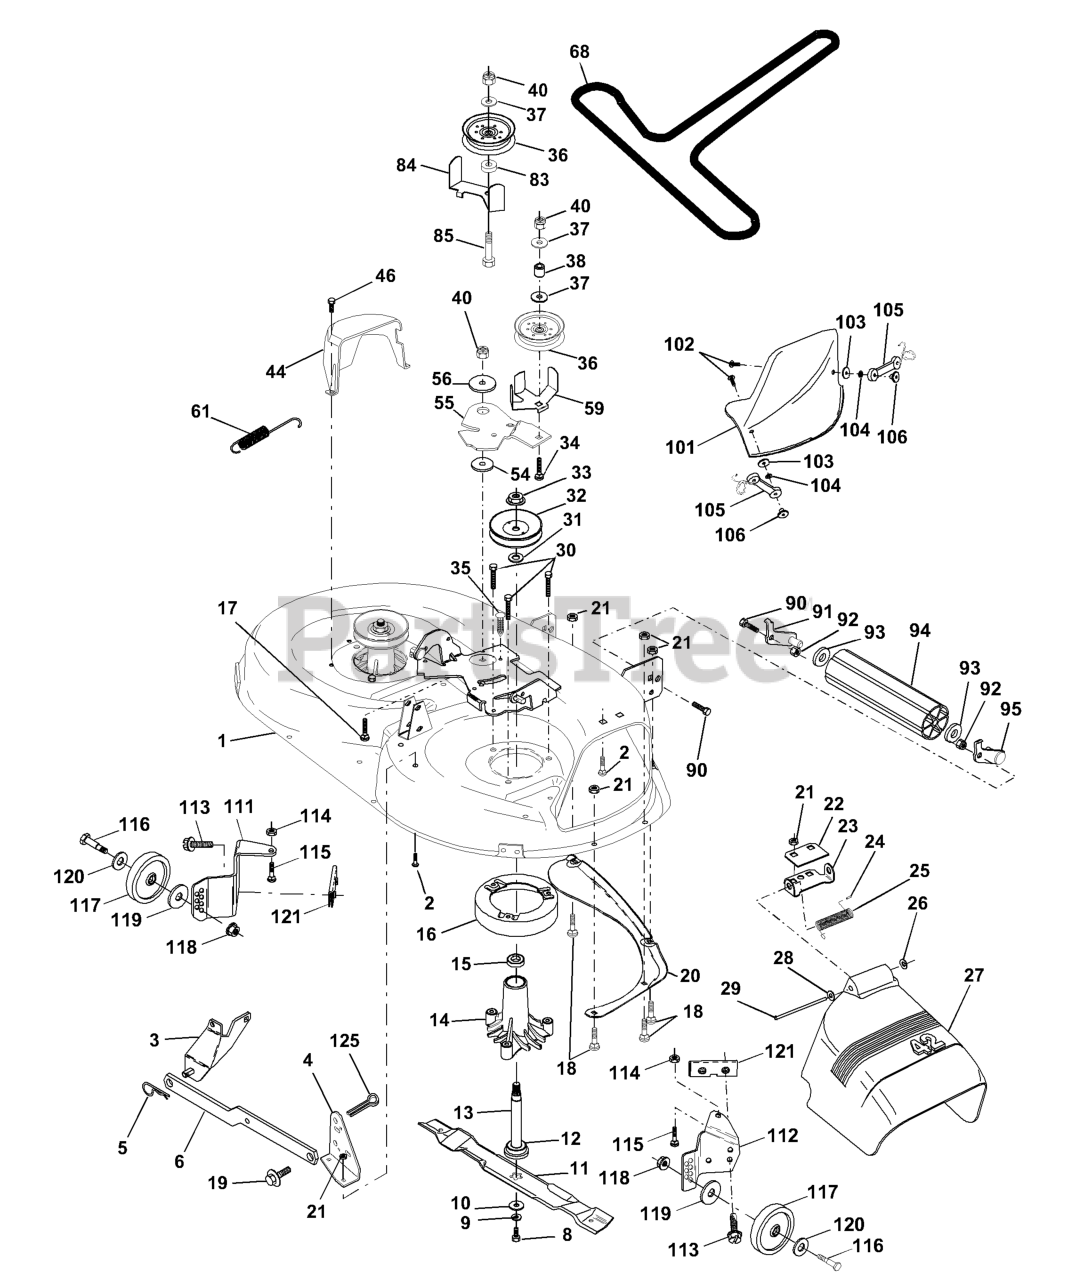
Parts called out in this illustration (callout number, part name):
1	DECK 42"
2	RP BOLT 5/16-18 X3/4 ZN/YEL GR
3	BRKT ASM SWAY BAR
4	BRKT DECK SW BAR
5	RETAINER-SPRNG RB
6	REAR SUSP ARM
8	BLADE BOLT
9	LOCKWASHER
10	WASHER.BLADE
11	BLADE.42".MULCH
12	BEARING.BALL.#6204.(MANDREL)
13	SHAFT ASM VENT
14	HOUSING.MANDREL.VENTED (MACHD)
16	STRIPPER
17	BOLT CARRIAGE
18	BOLT
19	BOLT SHD 5/16-18
20	BAFFLE
21	LOCKNUT
22	STIFFENER BRACKET
23	DEFLECTOR BRACKET
24	CAP-SLEEVE LT
25	SPRING TORSION
26	NUT PUSH M
27	SHIELD.DEFLECTOR.MOWER.42".BLK
28	Washer 11/32 X 5/8 X 16 Ga
29	ROD.HINGE
30	SCREW
31	WASHER
32	MANDREL PULLEY
33	NUT
35	FASTENER.XMAS.TREE
36	FLAT IDLER PULLEY
37	WASHER
38	IDLER SPRING SPACER
44	GUARD MANDREL LH BLACK
46	SCREW.1/4-20X5/8
54	HARDENED WASHER
55	IDLER ARM
56	SPACER RETAINER
59	GUARD, BELT
61	SPRING EXTENSION
68	V-BELT TRIPATH
84	KEEPER BELT
85	BOLT
90	BOLT
91	BRACKET LH (A)
92	NUT
93	Washer 17/32 X 7/8 X 16 Ga
94	NOSE ROLLER
95	BRACKET RH (B)
101	COVER MULCH 42"
102	SCREW
104	LOCKWASHER #10
105	LATCH ASSEMBLY
106	WELDNUT
111	BRACKET
112	BRACKET
113	SCREW.THDROL.5/16-18X3/4.TTY
114	NUT
115	BOLT.CARR.5/16-18X1/2
116	BOLT M
117	WHEEL.GAUGE.BLK.4.93
118	LOCKNUT
119	WASHER.5/16.FLAT.STE.STD.
120	Washer 17/32 x 15/16 x 12 Ga.
121	BRACKET.EXTRUDED.GAGE.WHEEL
125	Cotter Pin
